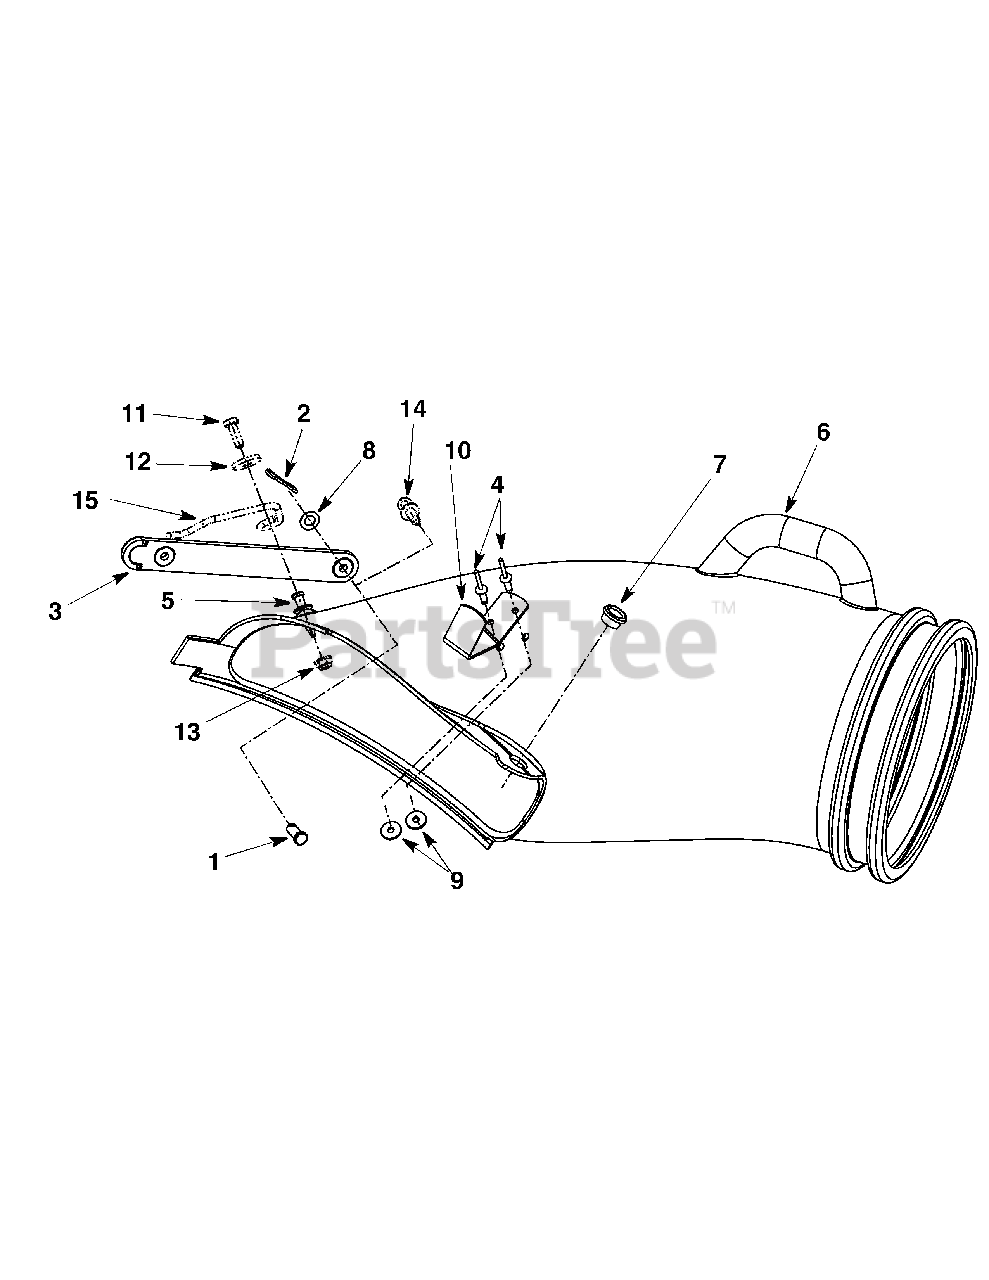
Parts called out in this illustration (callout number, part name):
1	PIN: CLEVIS: 5/16" x 3/4"
2	PIN: COTTER: BOW-TIE 72
3	STRAP: CHUTE: 6.00" LONG
4	RIVET: POP: .187 DIA.
5	RIVET: PLASTIC: .250
6	CHUTE: ELBOW: 33" GRASS BAG
7	BUSHING: ROD: CONTROL
8	WASHER: FLAT: .344 x .62 x .033
9	WASHER: FLAT: .194 x .62 x .063
11	SCREW: HEX HD: 1/4"-20 x .75: GR5: STD
12	WASHER: FLAT: .265 x .938 x .120
13	NUT: FLANGELOCK: 1/4"-20: GRF: NYLON
14	RIVET: PLASTIC: .3125 DIA.
